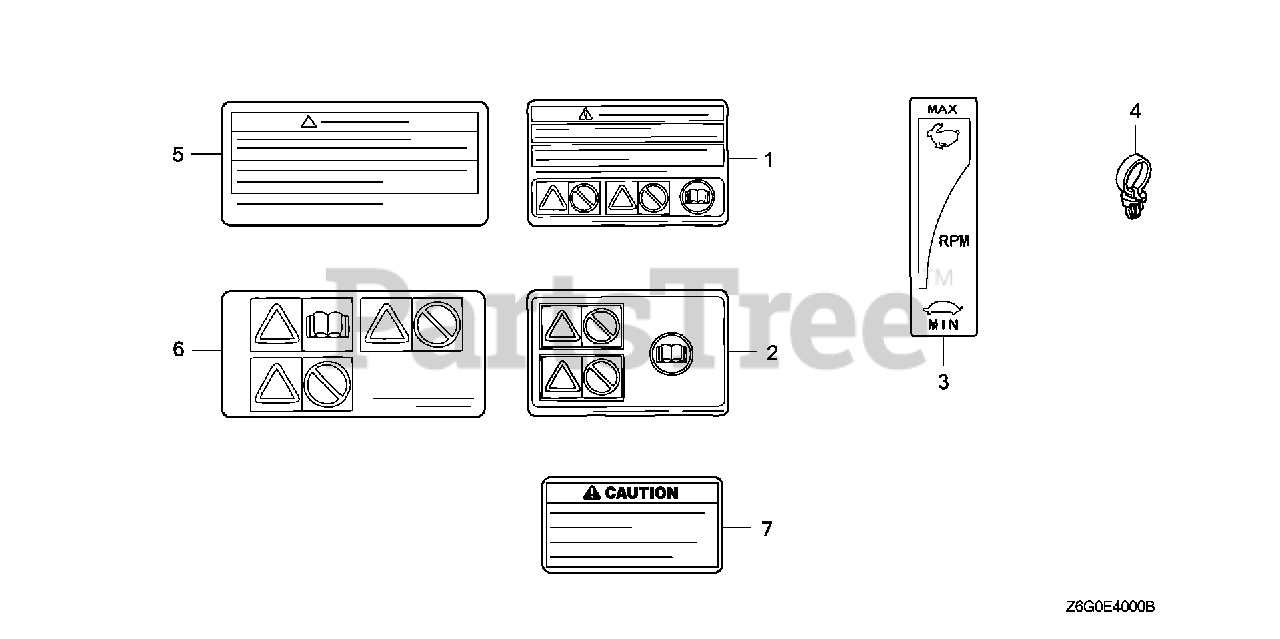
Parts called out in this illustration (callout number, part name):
1	MARK, OPERATOR CAUTION (FRENCH)(MADE IN JAPAN)
5	MARK, OPERATOR CAUTION (FRENCH)(MADE IN JAPAN)
6	MARK, OPERATOR CAUTION (PICTOGRAPH)
